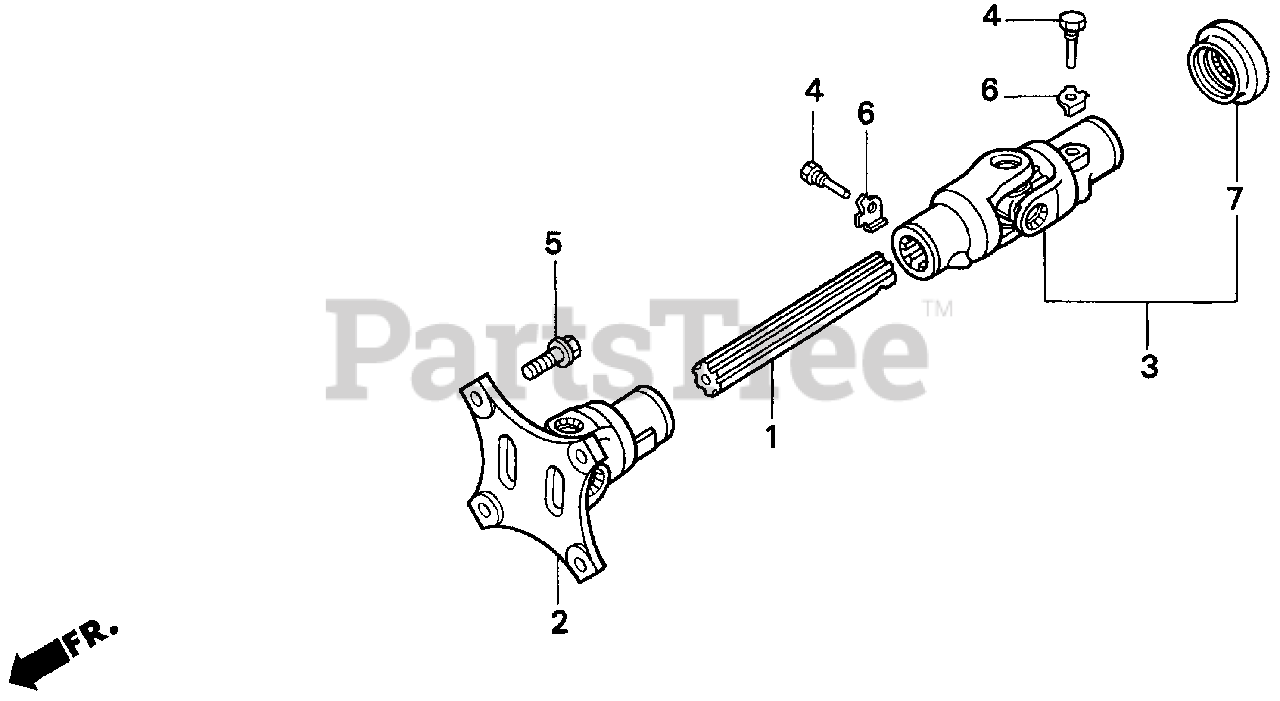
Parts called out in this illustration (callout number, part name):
1	SHAFT A, PROPELLER
2	JOINT A, UNIVERSAL
3	JOINT B, UNIVERSAL
4	BOLT, SPECIAL (8MM)
5	BOLT, HEX. (10X25)
6	WASHER, LOCK (8MM)
7	SEAL, SPLINE
